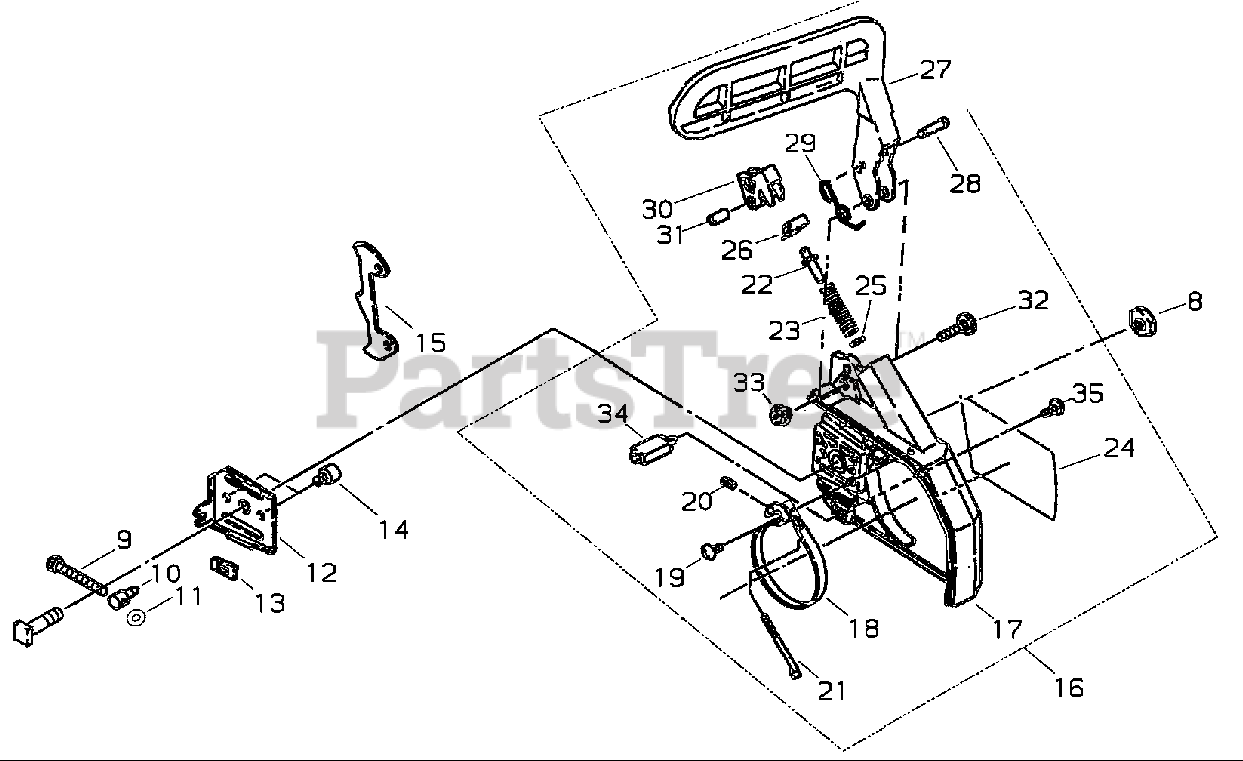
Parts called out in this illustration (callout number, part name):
8	NUT - 8
9	SCREW, SLIDE
10	TENSIONER, CHAIN
11	PUSHNUT
12	PLATE, INNER GUIDE
13	GUIDE
14	SCREW
15	SPIKE
16	CHAIN BRAKE ASSY
17	GUARD, SPROCKET
18	BAND, BRAKE
19	SCREW - 5X10
20	PIN - SPRING -- 4X12
21	BOLT, ADJUSTING - 6
22	SCREW, ADJUST
23	SPRING, BRAKE
24	LABEL - TRADE
25	WASHER - 6
26	RETAINER
27	LEVER, BRAKE
28	PIN - STOPPER
29	SPRING, BRAKE
30	LEVER, INNER
31	PIN, LEVER
32	BOLT
33	NUT
34	CATCHER, CHAIN
35	SCREW - 3X8
